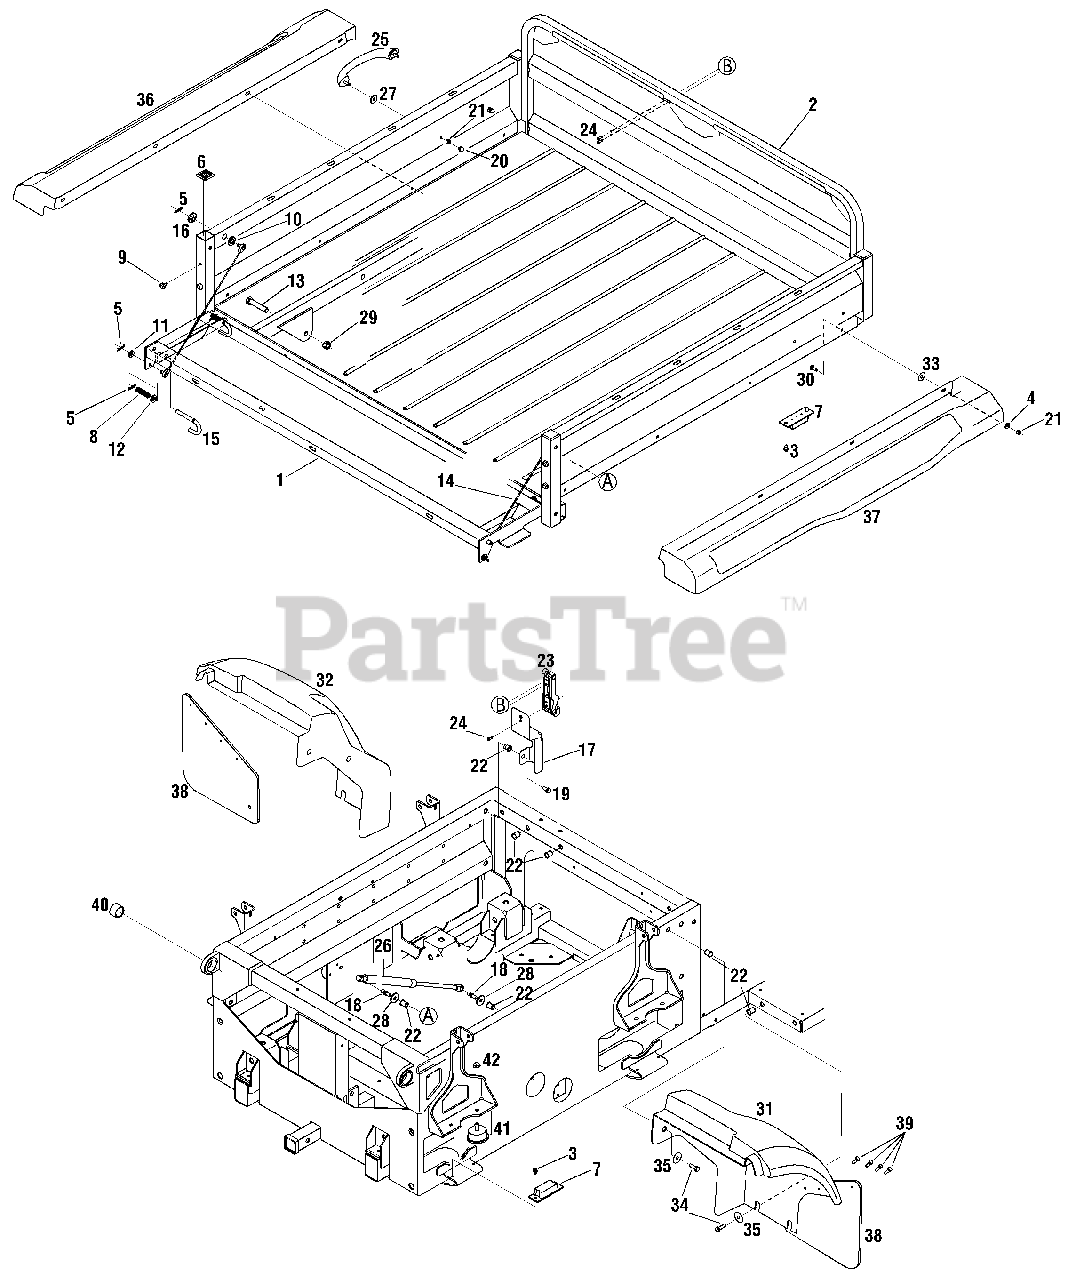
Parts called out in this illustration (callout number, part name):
1	Tailgate Assembly
2	Bed Assembly
3	Screw, Self-tapping, 1/4-20 x 0.500
4	Flat Washer, .271 x .630 x .065
5	Cotter Pin, .072 Dia x 1.13
7	Bumper, Extension Suspension
8	Compression Spring, .406 x .531 x
9	Bumper, .62Dia x .3
10	Washer, Flat, .64 ID x 1.0 x .12
11	Washer, Flat, .344 x .750 x .120
12	Washer, Flat, .407 x .812 x .135
13	Screw, Hex, 1/2-13 x 2.5
14	Cable, LIft 16.16 LG
15	Handle, Deck Release
16	Spacer, Shoulder .625 Dia x .324 Dia
17	Bracket, Bed Latch Base
18	Stud, Ball 5/16-18
19	Hex Screw, 5/16-18 x .625, Gr5
20	Nut, Acorn 1/4-20 w/o Lock
21	Nut, Hex Lock, 1/4-20
22	Nut, Insert 5/16-18
24	Pop Rivet, 3/16
25	Handle, Bag w/Screw
26	Spring, Gas .91 Stroke
27	Washer, Flat .265 x .938 x .120
28	Washer, Flat.344 x 1.125 x .120
29	Hex Lock Nut, 1/2-13
30	Hex Screw, 1/4-20 x .75
31	Fender, Rear RH, Camo
32	Fender, Rear LH, Camo
33	Rubber Washer, .310 x 1.0 x .125
34	Hex Screw, 5/16-18 x 1.0
35	Bell Washer, .39 x 1.38 x .062
36	Bed Skirt Panel, LH, Camo
37	Bed Skirt Panel, RH, Camo
38	Rear Mud Flap
39	Pop Rivet, .188
40	Rubber Bushing, Bed Pivot
41	Bumper, Compression Suspension
42	Hex Lock Nut, M10-1.25
